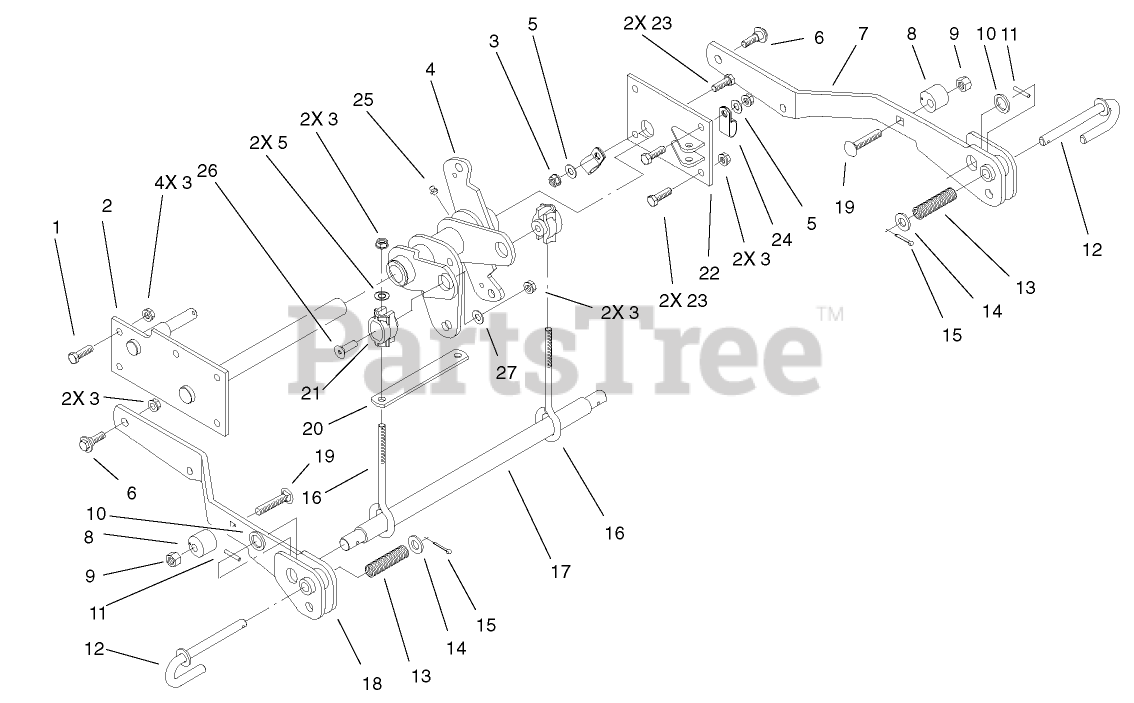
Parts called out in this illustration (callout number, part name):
1	SCREW-HH
2	SUPPORT-LIFT, DECK
3	NUT-LOCK, NI
4	BELLCRANK AND BUSHING ASM
5	WASHER-FLAT
6	SCREW-SHOULDER, HWH
7	ARM-LIFT, LH
8	STOP-LIFT, ADJ.
9	NUT-LOCK, NI
10	WASHER-FLAT
11	PIN-ROLL
12	PIN - J
13	SPRING-COMPRESSION
14	WASHER-FLAT
15	PIN-COTTER
16	ROD-LIFT
17	BAR-LIFT
18	ARM-LIFT, RH
19	SCREW-CARR
21	SLEEVE-LIFT
22	SUPPORT-CYLINDER
23	SCREW-HH
24	CLAMP-TUBE
25	FITTING-GREASE
26	SCREW-HSFH
27	WASHER-FLAT
